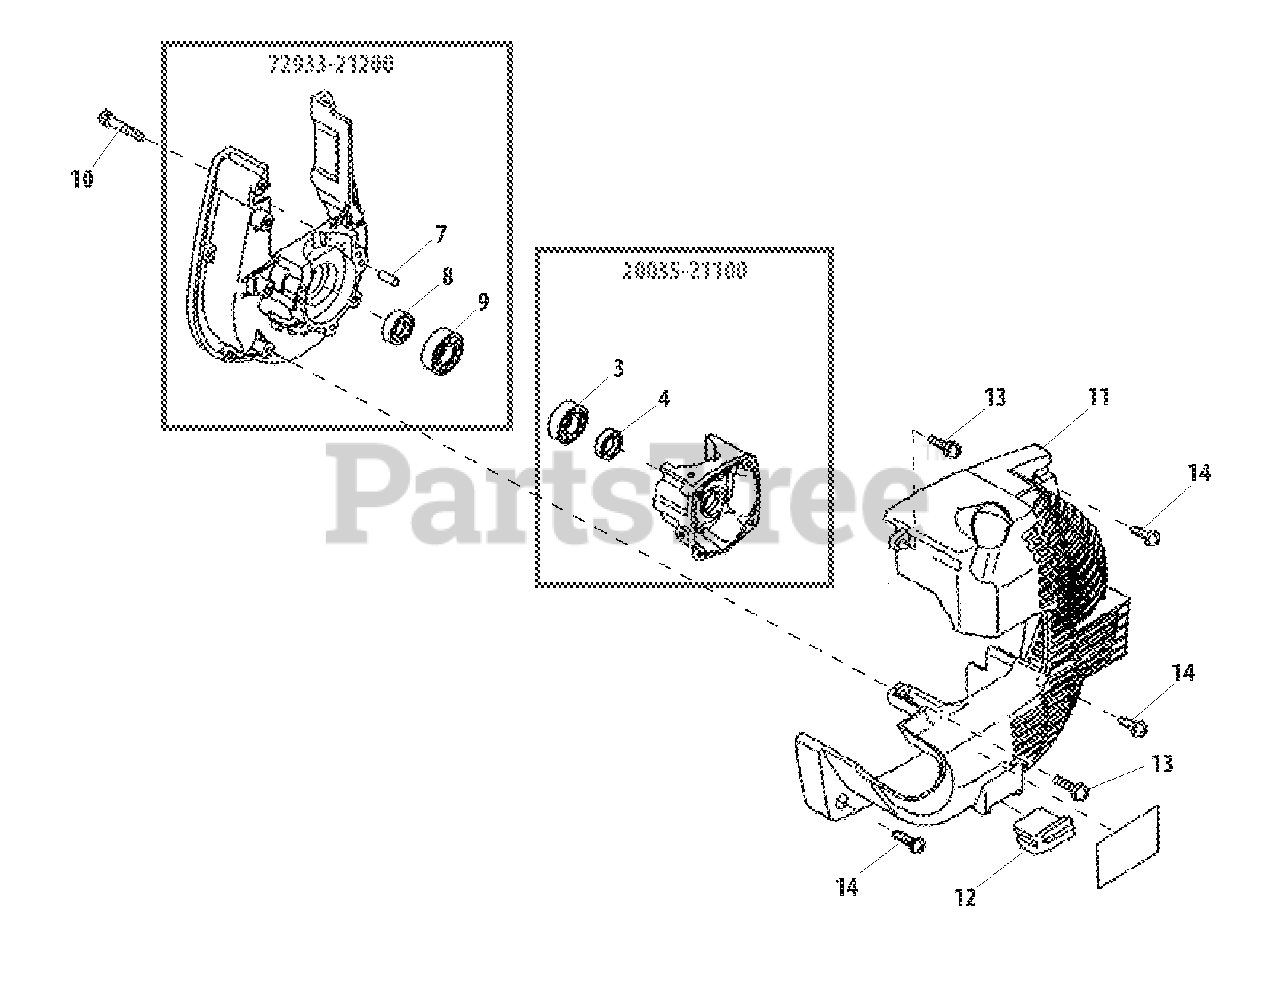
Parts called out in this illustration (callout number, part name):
3	BEARING, BALL - 6001C3
4	SEAL, OIL
7	PIN - LOCATING
8	SEAL, OIL - 12
9	BEARING, BALL - 6201C3
10	SCREW - 5X25
11	COVER, ENGINE
12	CUSHION
13	SCREW - 5X16
14	SCREW - 5X20
20035-21100	CRANKCASE ASSY - REAR
72933-21200	CRANKCASE ASSY - FRONT
